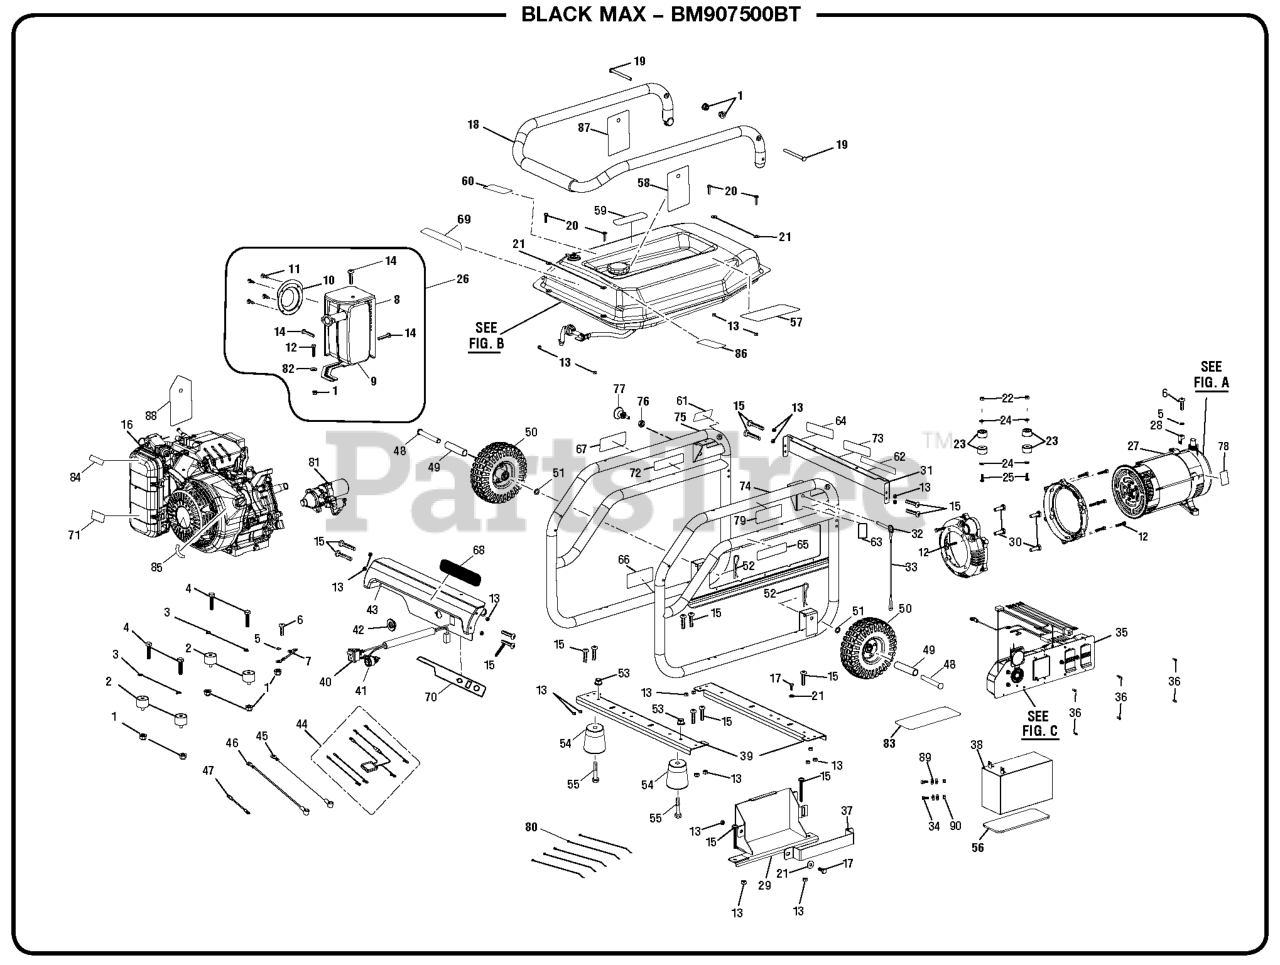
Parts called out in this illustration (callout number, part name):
1	Lock Nut (M8 x 1.25 in.)
3	Lock Washer (OD14.8 x ID8.5 x 1t)
4	Bolt (M8 x 35 mm, Hex Hd.)
5	Star Washer (M8)
6	Bolt (M8 x 15 mm, Hex Hd.)
7	Ground Wire Assembly
8	Heat Shield
9	Muffler w/Brackets
10	Spark Arrestor
11	Screw (8-32 x 3/8 in., Pan Hd.)
12	Bolt (M8 x 0 mm., Hex Hd.)
13	Lock Nut (M6)
14	Bolt (M6 x 9 mm, Hex Hd.)
15	Screw (M6 x 50 mm, T30 Torx Hd.)
17	Bolt (M6 x 16 mm, Hex Hd.)
18	Handle Assembly
19	Handle Pivot Bolt M8 x 98 mm, Flat Hd.)
20	Bolt (M6 x 25 mm, T30 Torx Hd.)
21	Washer (M6)
22	Lock Nut (M4)
23	Rubber Bumper
24	Washer (OD9 x ID4.3 x 1t)
25	Screw (M4 x 12 mm, Button Hd.)
26	Muffler Assembly
27	Generator Head (See Figure A)
28	Ground Lug
29	Battery Tray
30	Bolt (3/8-16 x 1 in., Hex Hd.)
31	Fuel Tank Support (Back)
32	Handle Lock Pin
34	Bolt (M5 x 10 mm, Hex Hd.)
35	Control Panel Assembly (See Figure C)
36	Screw (6-20 x 3/8 in., Pan Hd.)
37	Battery Bracket
39	Frame Crossbar
40	Wiring Harness
41	Engine Switch
42	Fuel Valve
43	Fuel Tank Support (Front)
44	Wiring Harness
45	Battery Cable (Black)
46	Battery Cable (Red)
47	Bonding Wire
48	Axle (M10 x 99 mm, Pan Hd.)
50	Wheel (10 in. x 3 in.)
51	Washer (OD19.75 x ID10.5 x 1t)
52	Hitch Pin
53	Lock Nut (M8 x 1.25)
54	Rubber Foot
55	Bolt (M8 x 45 mm, Hex Hd.)
57	CPSC Label
58	Warning Hangtag
59	Danger Icon Label
60	E85 Label
61	Handle Release Label
62	Ground Warning Label
63	Lock Pin Label
64	Inquiries Label
65	Lubricant Label
66	Combustion Label
67	Fire Distance Label (SP/ENG)
68	Logo Label
69	Black Max Label
70	Start Label
71	Electric Start Label
72	Hot Surface Label
73	Fire Danger Label
74	Frame (Right
75	Frame (Left)
76	Hex Jam Nut (1/2-20)
77	Handle Release Pin
78	Ground Label
79	Maxcontrol Label
80	Zip Tie (5-1/2 in.)
81	12V Electric Start Motor
82	Washer (OD25.4 x ID8x 1t)
83	Rubber Sheet
84	Choke Label
85	Engine Secondary On/Off Label
86	Remove Cap Fuel Stablizer Label.
87	Black Max Bluetooth Hangtag
88	Toggle Reset Label
89	Washer (OD10 x ID5.3 x 0.5t)
